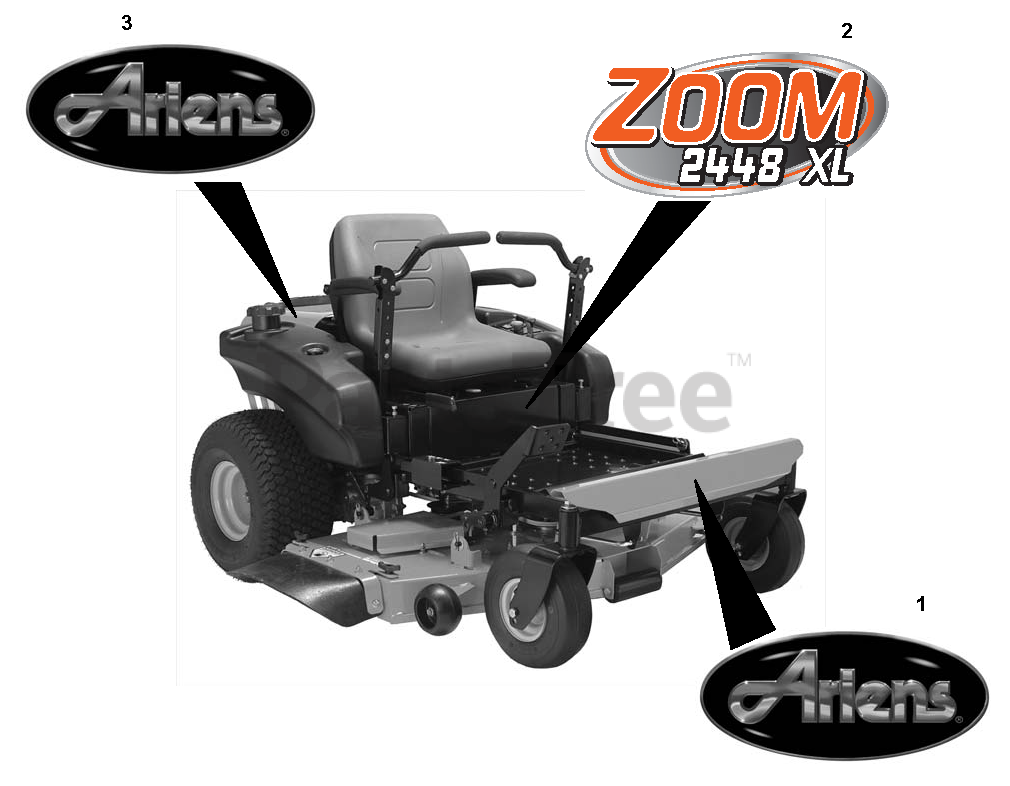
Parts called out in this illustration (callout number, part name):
1	DECAL, ARIENS JEWEL (LARGE)
2	DECAL, 2448 ZOOM XL
3	DECAL, ARIENS JEWEL
